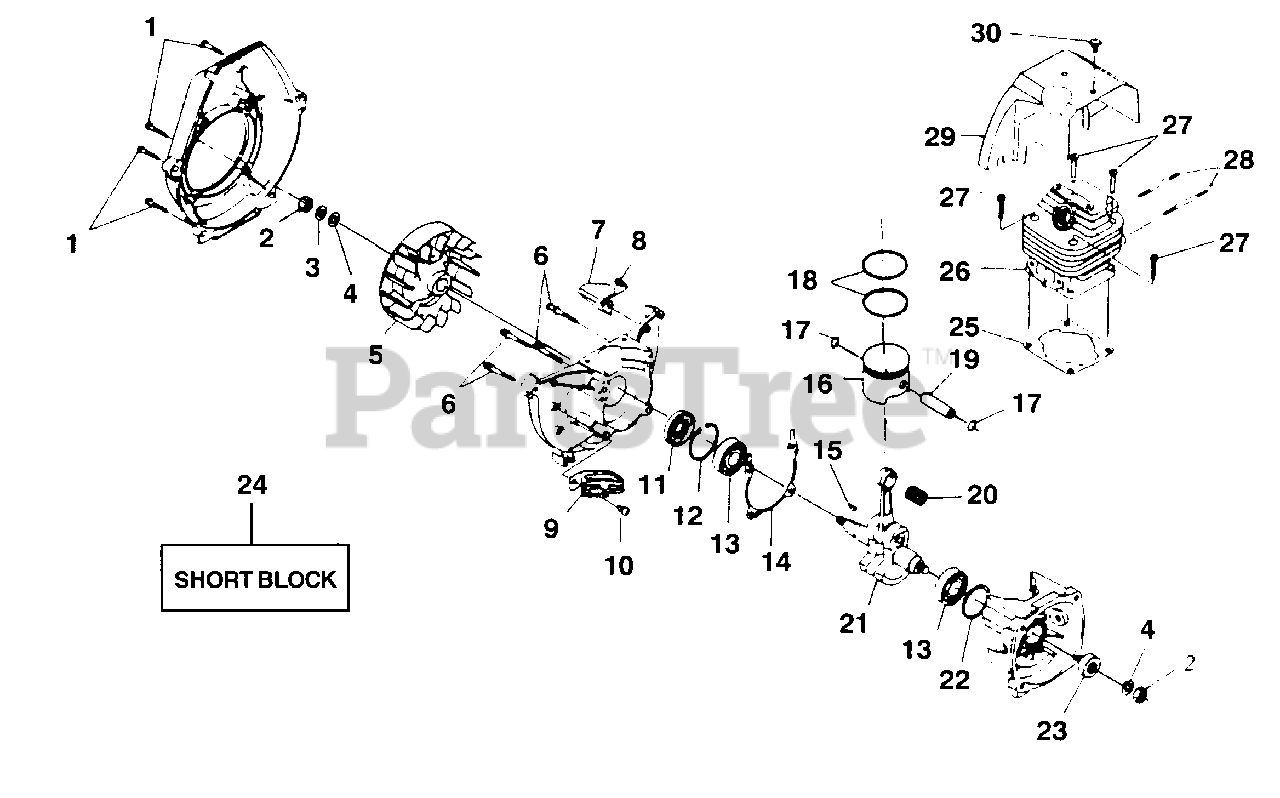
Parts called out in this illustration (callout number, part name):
1	SCREW
2	NUT
3	WASHER, SPG
6	SCREW & WASHER
8	SCREW & WASHER
10	SCREW & WASHER
12	SNAP RING
13	BEARING, BALL
14	GASKET, CRANKCASE
15	KEY, WOODRUFF
17	CLIP, PISTON PIN
18	RING, PISTON
19	PIN, PISTON
20	NEEDLE BEARING
21	CRANKSHAFT ASSY
23	OIL SEAL
24	SHORT BLOCK
25	GASKET, CYLINDER
27	BOLT
29	CYL COVER
30	SCREW & WASHER
